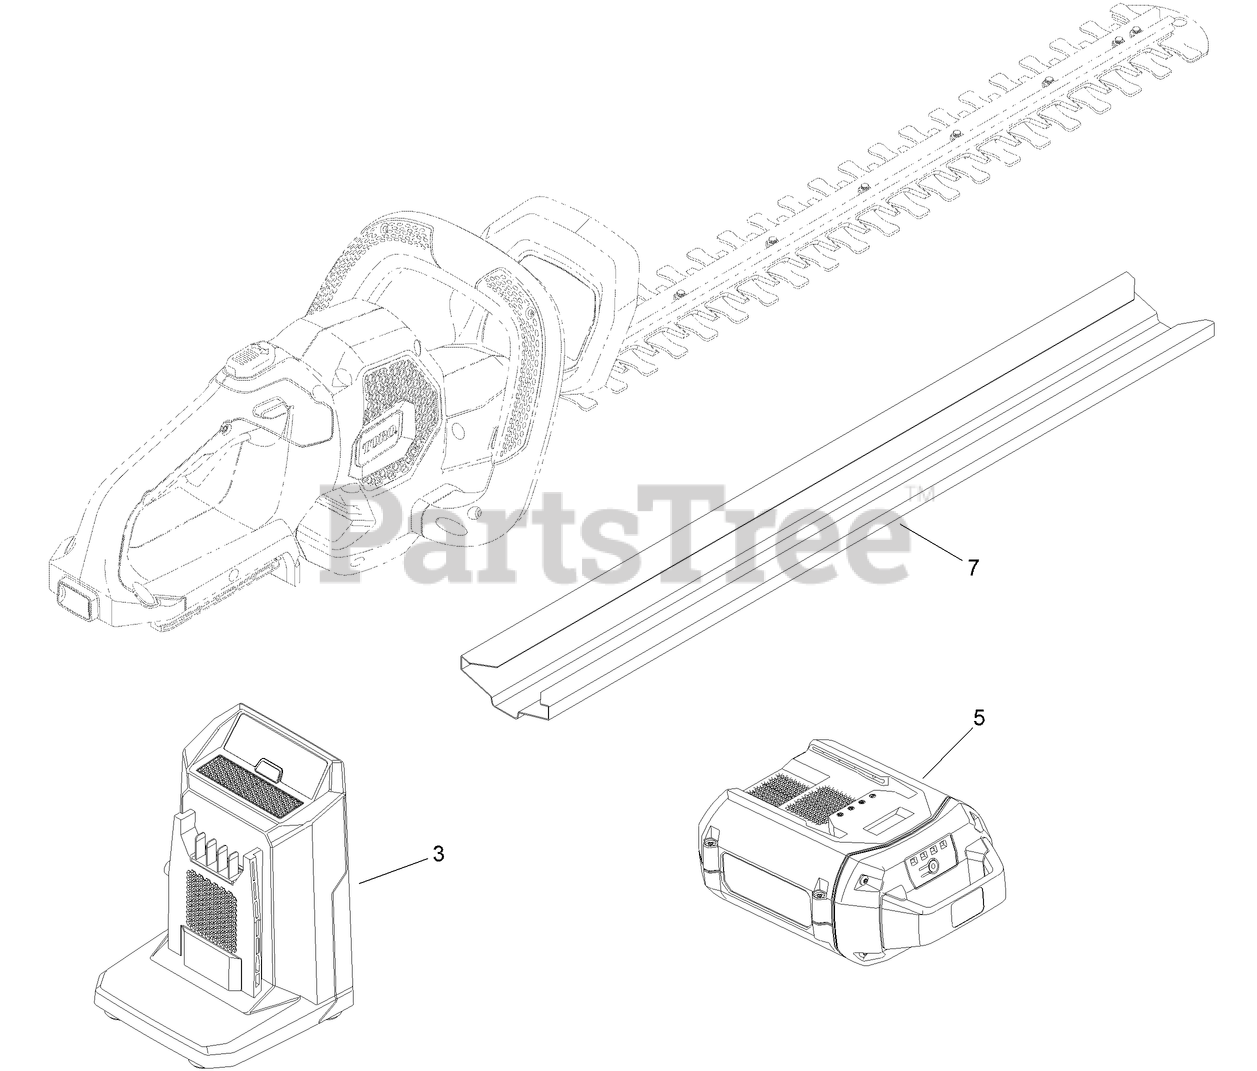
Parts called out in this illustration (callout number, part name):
3	CHARGER-BATTERY, 60V 2 AMP
5	BATTERY-LI ION, 60V 2.5 AH
7	SLEEVE-BLADE
